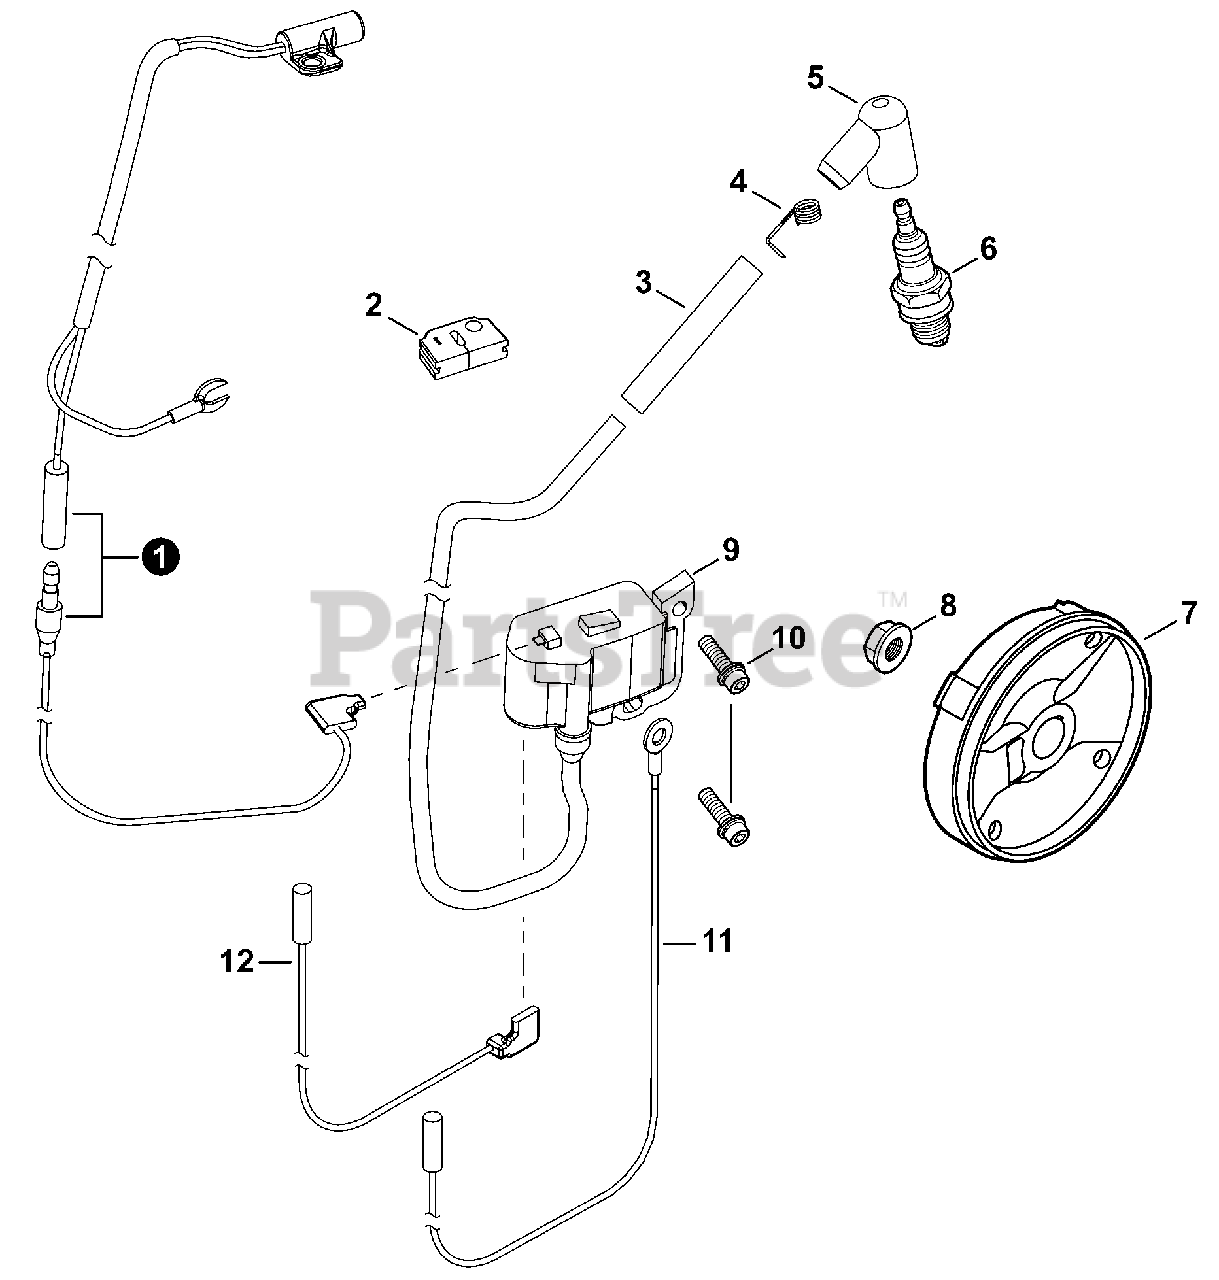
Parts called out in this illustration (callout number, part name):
1	SENSOR, THERMAL
2	GROMMET
3	TUBE, INSULATOR
4	TERMINAL, SPARK PLUG
5	CAP, SPARK PLUG
6	SPARK PLUG - CMR5H
7	FLYWHEEL
9	COIL, IGNITION
10	BOLT 4×20
11	LEAD - GROUND
12	LEAD 0.75 MM2 L= 175
